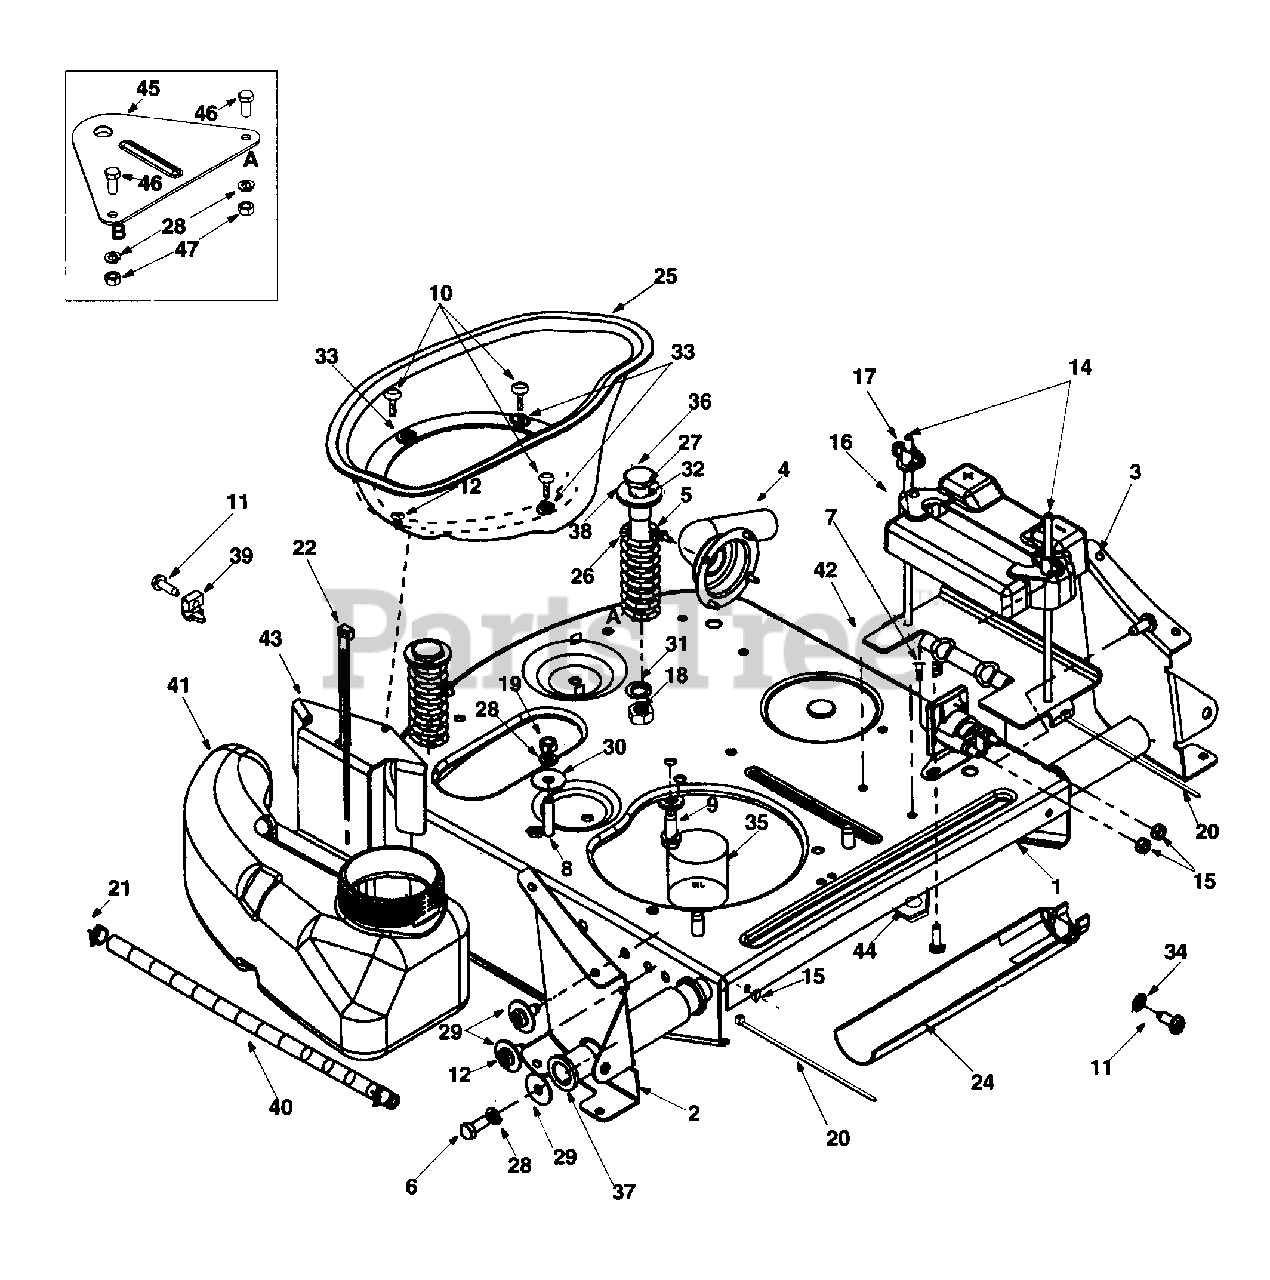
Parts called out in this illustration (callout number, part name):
3	Frame Rail Support: LH
4	Muffler Pipe Extension
5	Hex Fl. Screw #8-32 x 0.375
6	Hex Screw 5/16-24 x.75" Gr.5
7	Self-Tapping Screw
8	Hex Screw 5/16-24 x 1.5" Gr.5
9	TT Screw 3/8-16 x 1.0"
10	Hex Slot Sems Screw #10-32 x 0.38
11	Hex Washer TT Screw #10-32 x 0.625"
12	TT Screw 5/16-18 x 0.75"
14	Battery Hold-Down Rod
15	Hex Sems Nut 1/4-20
16	Battery Cover
17	Wing Nut with Bell Washer
19	Hex Nut 5/16-24 Gr.5
20	Cable Tie
21	Hose Clamp
22	Cable Tie
24	Oil Drain Sleeve
25	Engine Duct
26	Compression Spring
27	Rubber Washer
28	Lock Washer
29	Flat Washer
30	5/16 Washer
31	Lock Washer
32	Flat Washer
33	Flat Washer
34	Lock Washer
35	Motor Oil
36	Shoulder Screw
37	Flange Bearing
38	Flange Bearing
39	Throttle Casing Clamp
40	Fuel Line Hose
41	Fuel Tank
42	Battery Bracket
46	Hex Bolt: 5/16-18 x .75"
47	Hex Nut
